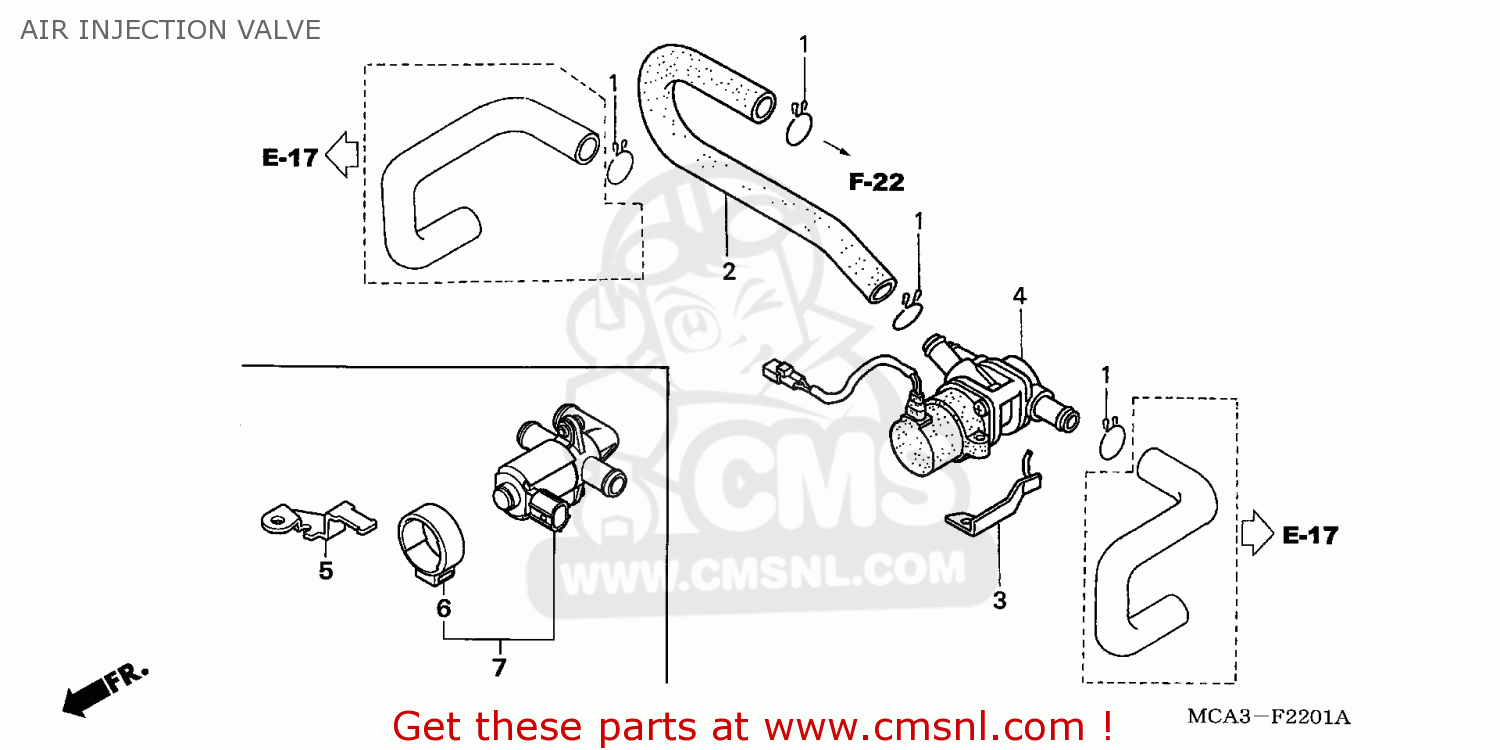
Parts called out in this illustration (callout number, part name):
1	CLIP,TANK HOSE
2	TUBE AI A
3	STAY SOLENOID
4	VLV ASSY,EX-AI
